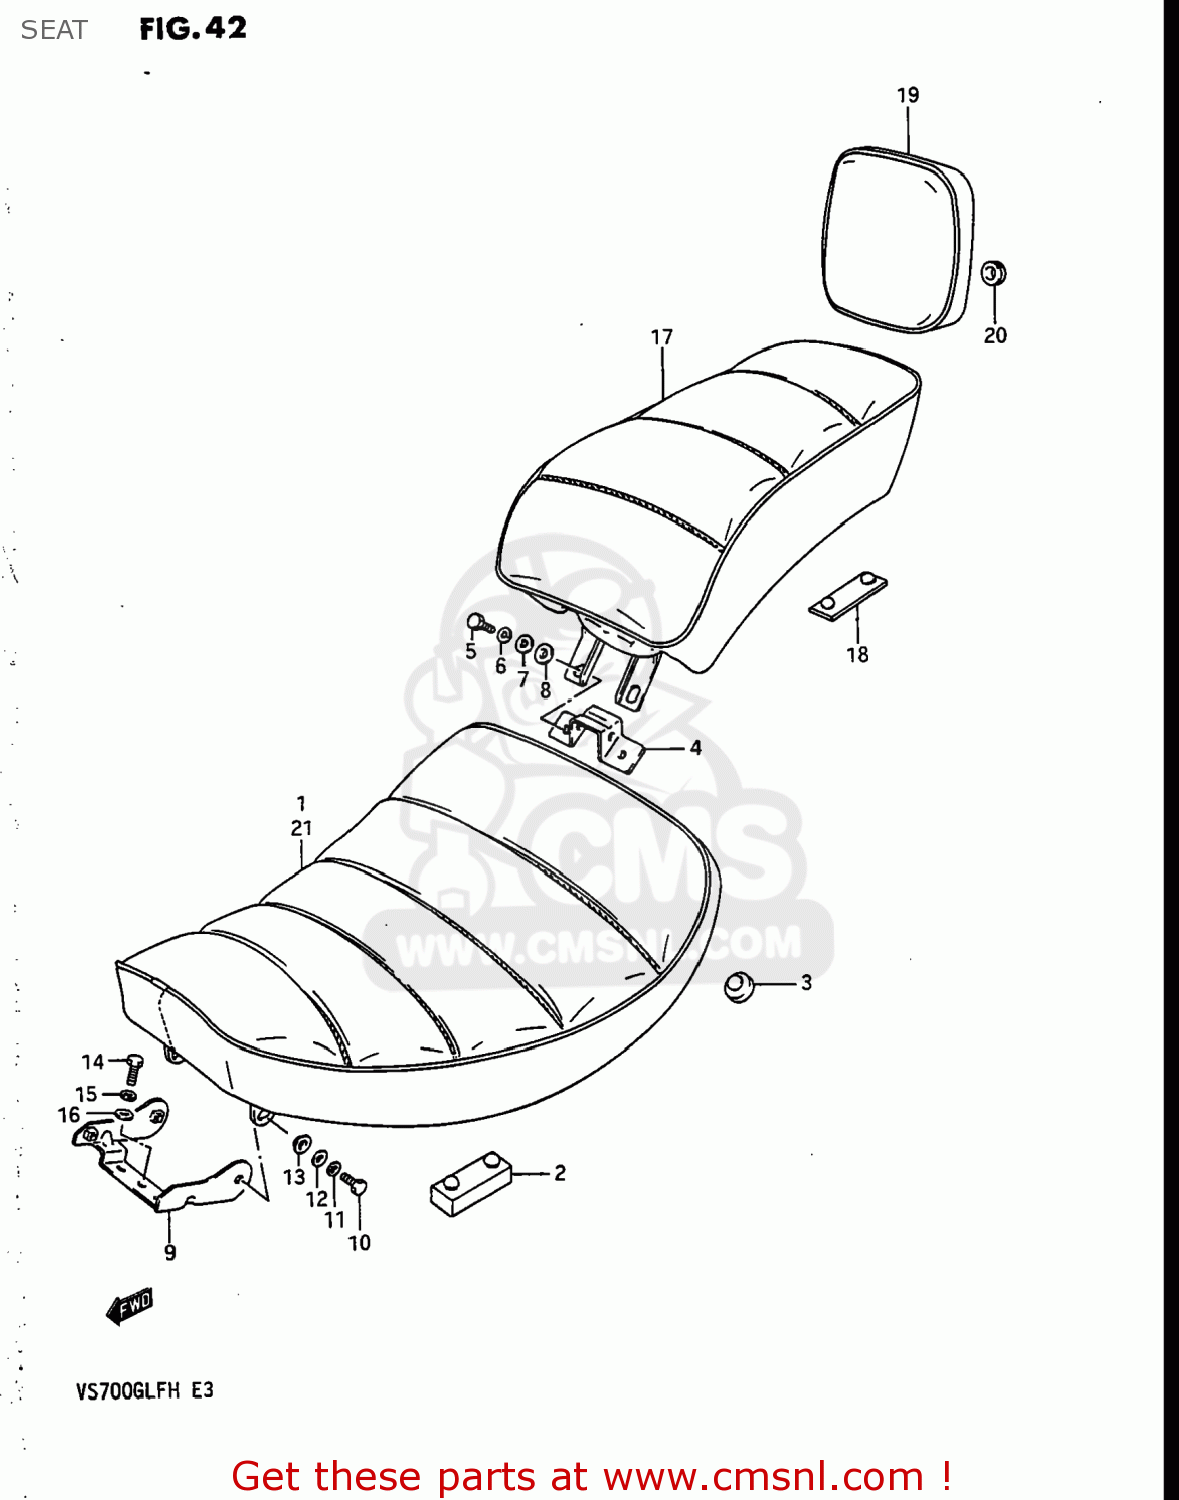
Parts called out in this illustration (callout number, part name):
1	SEAT ASSEMBLY
2	CUSHION,SEAT
3	CUSHION
4	PLATE,FR SEAT HOOK & RR
5	BOLT
6	WASHER,LOCK
7	WASHER, LOWER
8	WASHER
9	BRACKET,SEAT,FRONT
10	BOLT
11	WASHER,LOCK
12	WASHER, LOWER
13	WASHER
14	BOLT 6X16
15	WASHER,LOCK
16	WASHER
17	SEAT SET,PILLION
18	CUSHION
19	PAD ASSY,SEAT
20	CUSHION
21	SEAT ASSEMBLY
